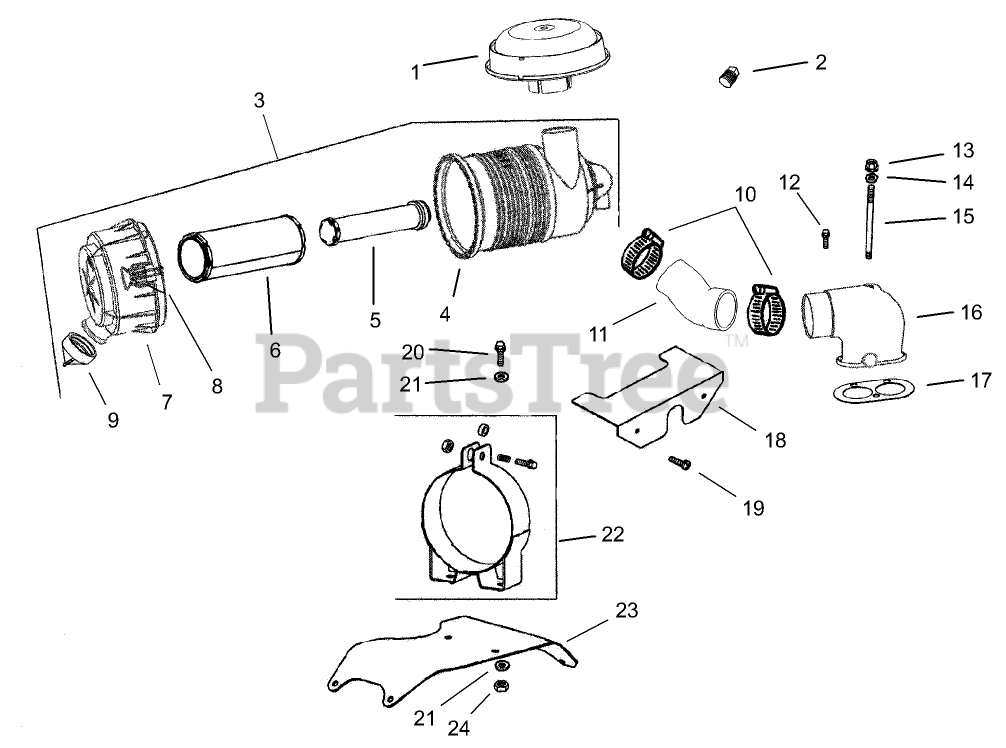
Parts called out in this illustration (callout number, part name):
1	Air Cleaner Bracket ASM
2	Plug-Pipe
3	Cleaner assembly, heavy-duty air (Includes 4-9)
4	Housing-Air Cleaner, Heavy Duty
5	Element-Air Filter, Safety
6	Element-Air Filter, Primary
7	Cover assembly, heavy-duty air (Includes 8,9)
8	Clip-Mounting
9	Valve-Ejector, Dust
10	Clamp-Hose
11	Hose-Cleaner, Air
12	Screw-HSH
13	NUT-FLANGE (M6X1.0)
14	Washer-Copper
15	STUD-CARBURETOR (M6X1.0X122)
16	Adapter-Intake, Air
17	Gasket-Base, Air Cleaner
18	Shield-Debris
19	SCREW-PPH (11-16X3/4)
20	Screw-HF (M6x1.0x16)
21	Washer-Flat (1/4)
22	Air Cleaner Bracket ASM
23	Bracket, Air Cleaner
24	Nut-Lock (M6X1.0)
